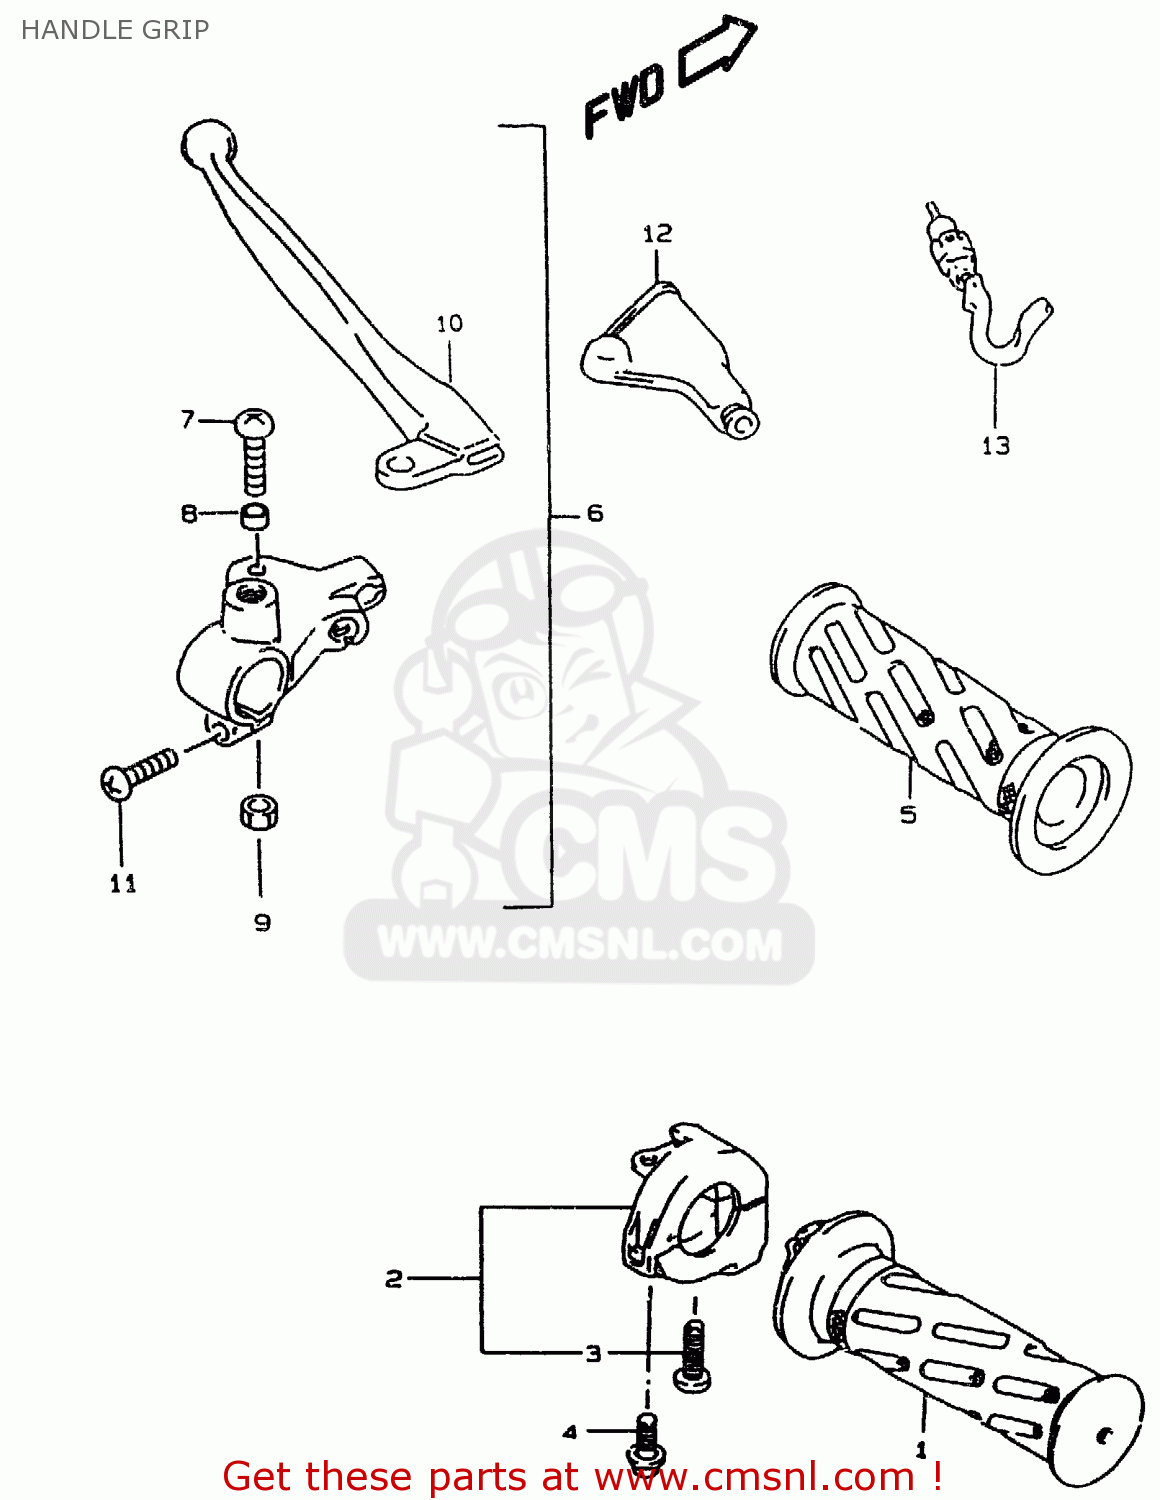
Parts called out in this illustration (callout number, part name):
1	GRIP, THROTTLE
2	CASE ASSY, THR
3	SCREW
4	SCREW(5X16)
5	GRIP, LH.
6	LEVER ASSY,RR
7	SCREW
8	SPACER
9	NUT
10	LEVER
11	SCREW, 6X20
12	COVER, LH
13	SWITCH,BRAKE
